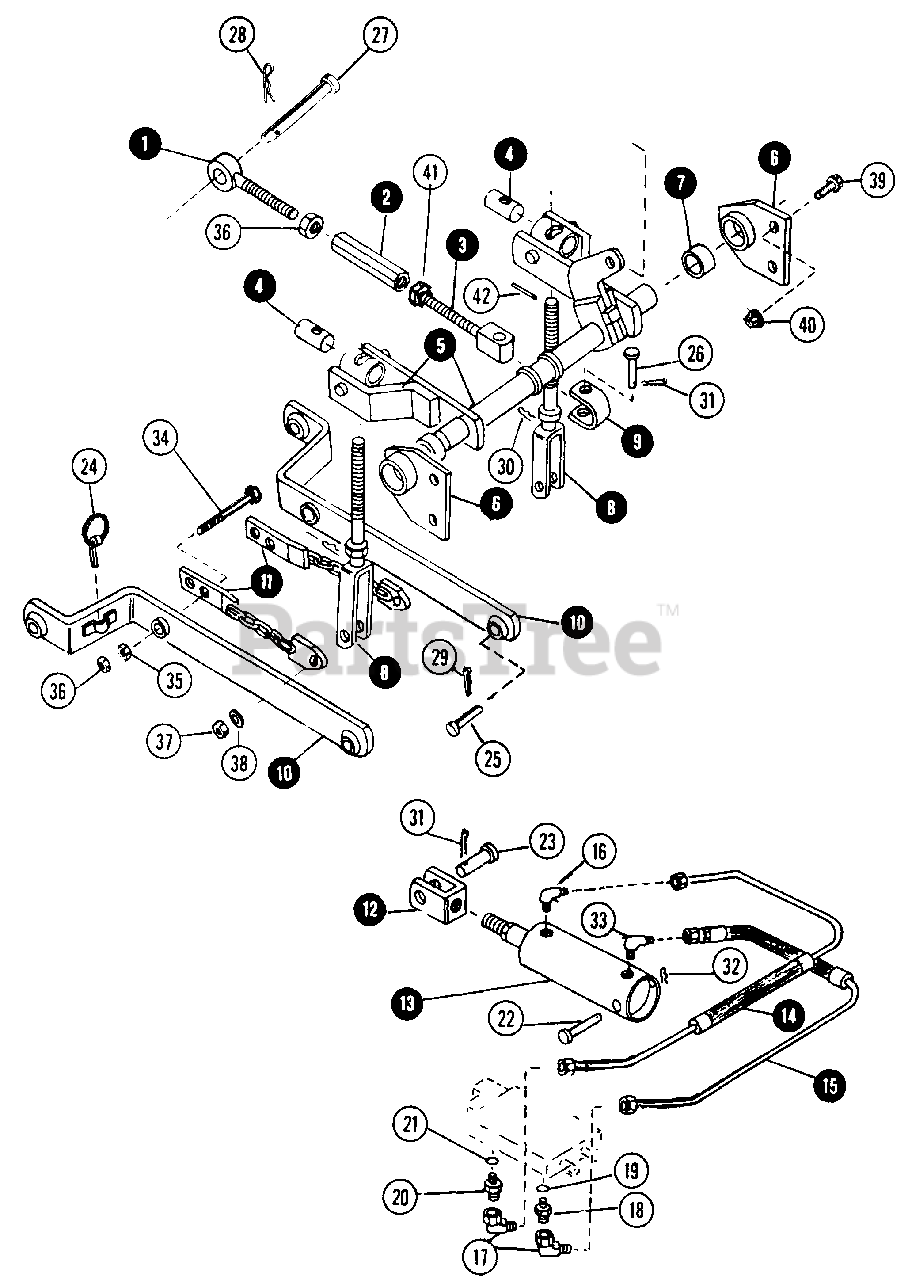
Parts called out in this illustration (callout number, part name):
1	CLEVIS, LINK ADJUSTER
2	ADJUSTER, UPPER LINK
3	CLEVIS, UPPER
4	SWIVEL, LOWER LINK
5	ROCKER - SHAFT,
6	PIVOT, ROCKERSHAFT
7	BUSHING, PIVOT
8	LINK, LOWER ADJUSTER
9	STRAP, CLEVIS TO SHAFT
10	LINK, LOWER LIFT
11	CHAIN, CHECK
12	END, CYLINDER ROD
13	CYLINDER, HYDRAULIC LIFT
14	TUBE & HOSE ASSEMBLY - VALVE TO CYLINDER
15	TUBE & HOSE ASSEMBLY - VALVE TO CYLINDER
16	ELBOW, 1/4-18
17	ELBOW, 90 DEGREE SWIVEL
18	CONNECTOR, ELBOW TO VALVE
19	O-RING, 906 (.08 x .47 I.D.)
20	CONNECTOR
21	O-RING, 908 (.09 x .64 I.D.)
22	PIN, CLEVIS - CYLINDER TO FRAME
23	PIN, CLEVIS - LINK TO FRAME
24	PIN,
25	PIN, CLEVIS - LINK TO FRAME
26	PIN, CLEVIS - CLEVIS TO SHAFT
27	PIN, CLEVIS - 5/8 x 3"
28	PIN, HAIR
29	COTTER-PIN, 3/16 x 1-1/4
30	PIN, HAIR - CLEVIS TO SHAFT
31	COTTER-PIN, 5/32 x 1
32	PIN, HAIR - CYLINDER to FRAME
33	ELBOW, 1/4-18 Extra Long
34	BOLT, 5/8C x 3-1/2 HEX HEAD
35	NUT, 5/8C HEX
36	NUT, 5/8C HALF HEX
37	NUT, 3/8C HEX LOCK
38	WASHER, 3/8" Flat
39	BOLT, 1/2C x 1-1/4 HEX WASHER HEAD
40	NUT, 1/2C HEX FLANGE
41	JAM-NUT, 5/8C LEFT HAND THREAD
42	PIN, 1/4 x 2-1/2 GROOVE
